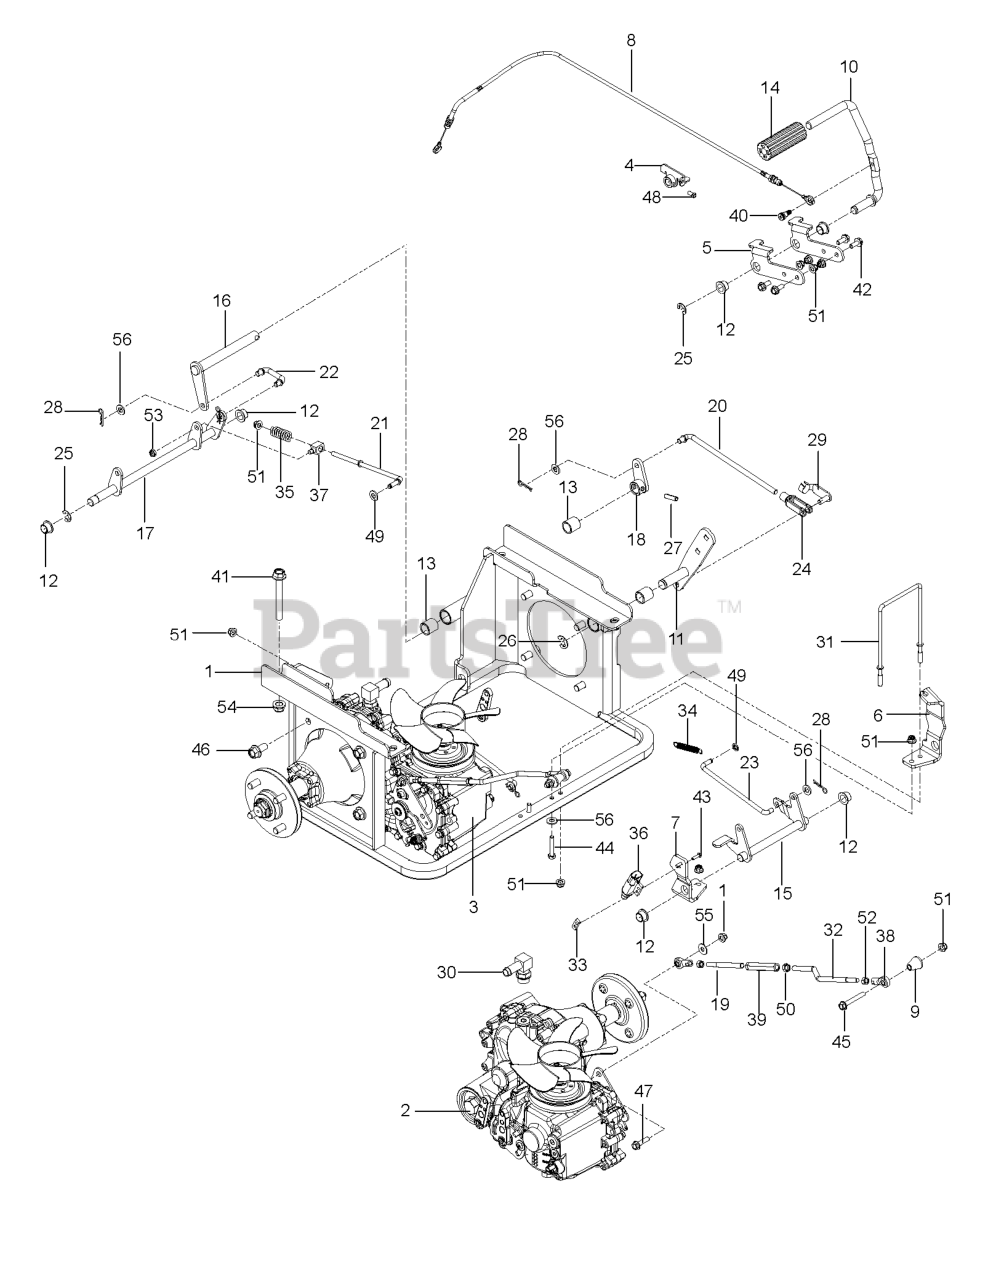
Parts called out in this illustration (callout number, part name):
1	FRAME, ZT5400, BLACK
2	HG_ZT5400, LT
3	HG_ZT5400, RT
4	BRACKET, CABLE, WELDED
5	BRACKET, PEDAL
6	BRACKET, TWO SPEED, LT
7	BRACKET, TWO SPEED, RT
8	CABLE, TWO SPEED
9	SPACER, TAPPERED, 1.0"
10	LEVER, PEDAL
11	LEVER, LOWER, BRAKE
12	BUSHING, FLANGE, 5/8
13	BUSHING, SLEEVE 3/4 X 1.0
14	PAD, FOOT PEDAL
15	CRANK, TWO SPEED
16	SHAFT, BRAKE, WELDED
17	SHAFT, BRAKE LOWER, WELDED
18	ARM, RT BRAKE
19	LINKAGE, CONTROL, FT
20	LINKAGE, BRAKE, UPPER
21	LINKAGE, BRAKE, LOWER
22	LINKAGE, BRAKE, MIDDLE
23	LINKAGE, TWO SPEED
24	YOKE-3/8-24 PLTD
25	E-RING 5/8
26	E RING 3/4
27	5/16 DIA ROLL PIN
28	HAIRPIN #2
29	PIN, CLEVIS SPRING, 3/8
30	FITTING, 4601-10-10 NOW
31	ROD, BELT KEEPER
32	ROD, CONTROL
33	TAPPED PLATE
36	SWITCH, PLUNGER, SEALED
37	SWIVEL, BRAKE
38	BALL JOINT, RIGHT HANDED
39	TURNBUCKLE, 3/8
40	BOLT, SHLD 3/8 X 5/16, 5/16-18
41	HHFS 1/2-13 X 4.0 GD8 ZD
42	HHFS 5/16-18 X 3/4
43	SCR #10-24 X .75 SKT HD BLK
44	HCS 5/16C X 1 3/4
45	HHFS 5/16-18 X 2.25 GD 5
46	HHFS 1/2-13 X 1 GR5 ZD
47	HHFS 5/16-18 X 1.25 TPBLT GD 5
48	SCREW 5/16C X 5/8 SQ HEAD
49	PUSH NUT
50	NUT 3/8-24 JAM
51	5/16-18 NYLOC FLANGE NUT
53	5/16-18 THIN PROF NY
54	NUT, 1/2-13 HEX FLG NYLOC ZD
55	WASHER 5/16 FLAT
56	WASHER 3/8 SAE FLAT
